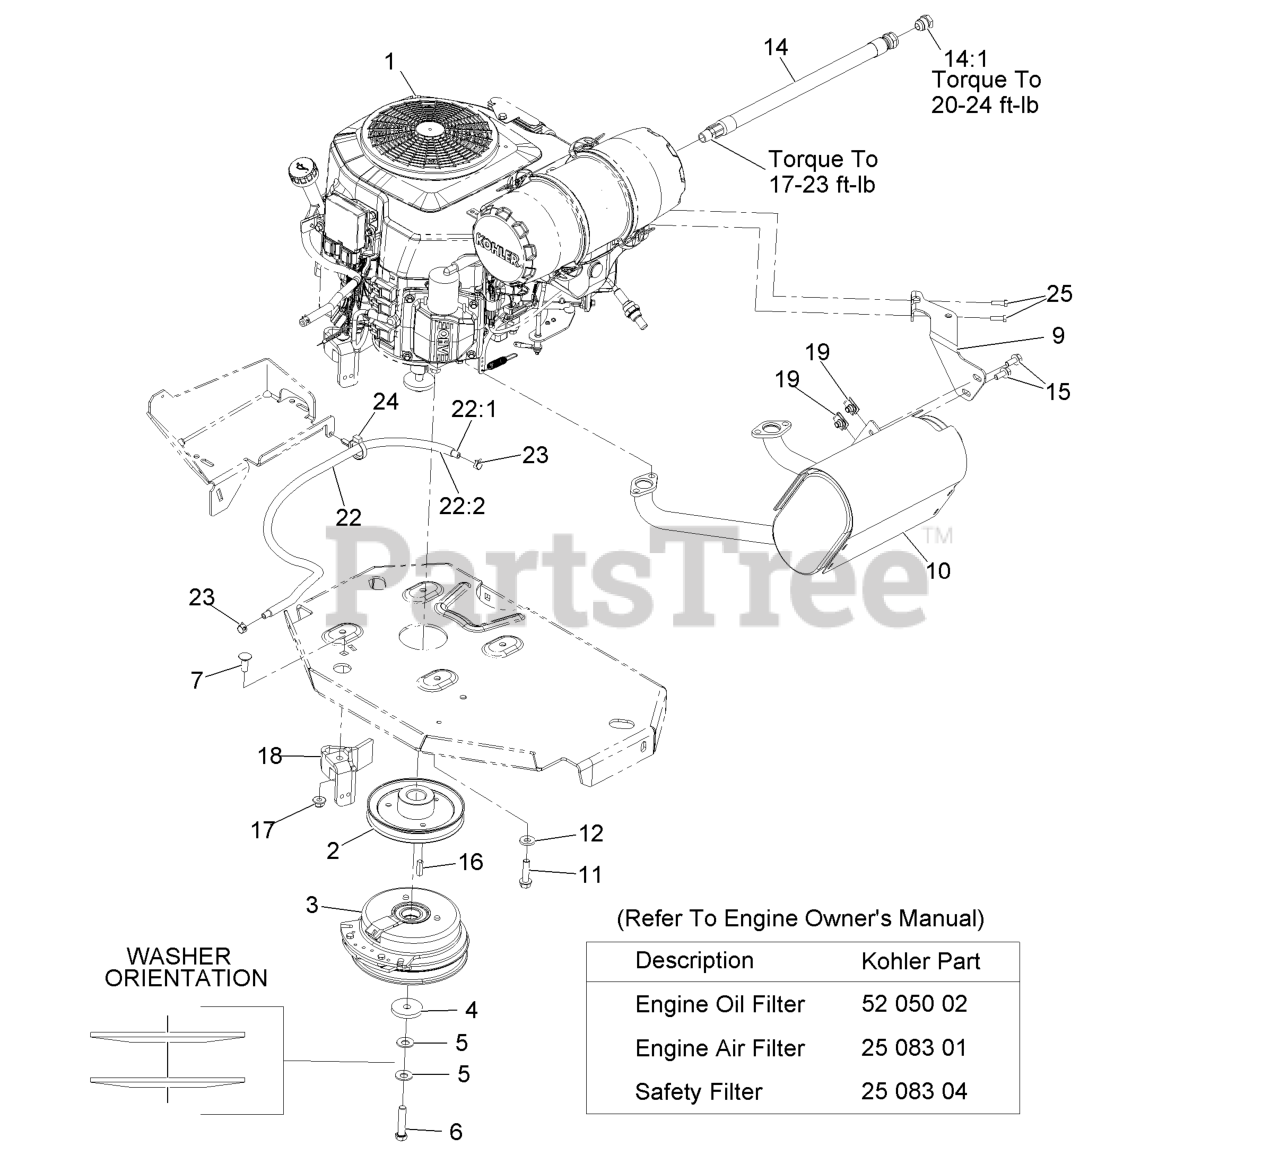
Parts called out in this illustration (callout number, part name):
1	Engine,Kohler
2	SHEAVE
3	CLUTCH KIT
4	WASHER-CLUTCH
5	WASHER-SPRING
6	SCREW-HH W/LOCTITE
7	SCREW-CARR
9	MUFFLER BRACKET KIT
11	SCREW-HWH
12	WASHER-BELLEVILLE
15	SCREW-HHF
17	NUT-HF, NI
18	CLUTCH-ANCHOR
22	FUEL LINE ASM
22:1	HOSE-FUEL
22:2	SLEEVE-THERMAL
23	CLAMP-HOSE
24	CLAMP-HOSE
25	SCREW-HH M6-1 X 20Mm W/Patch
